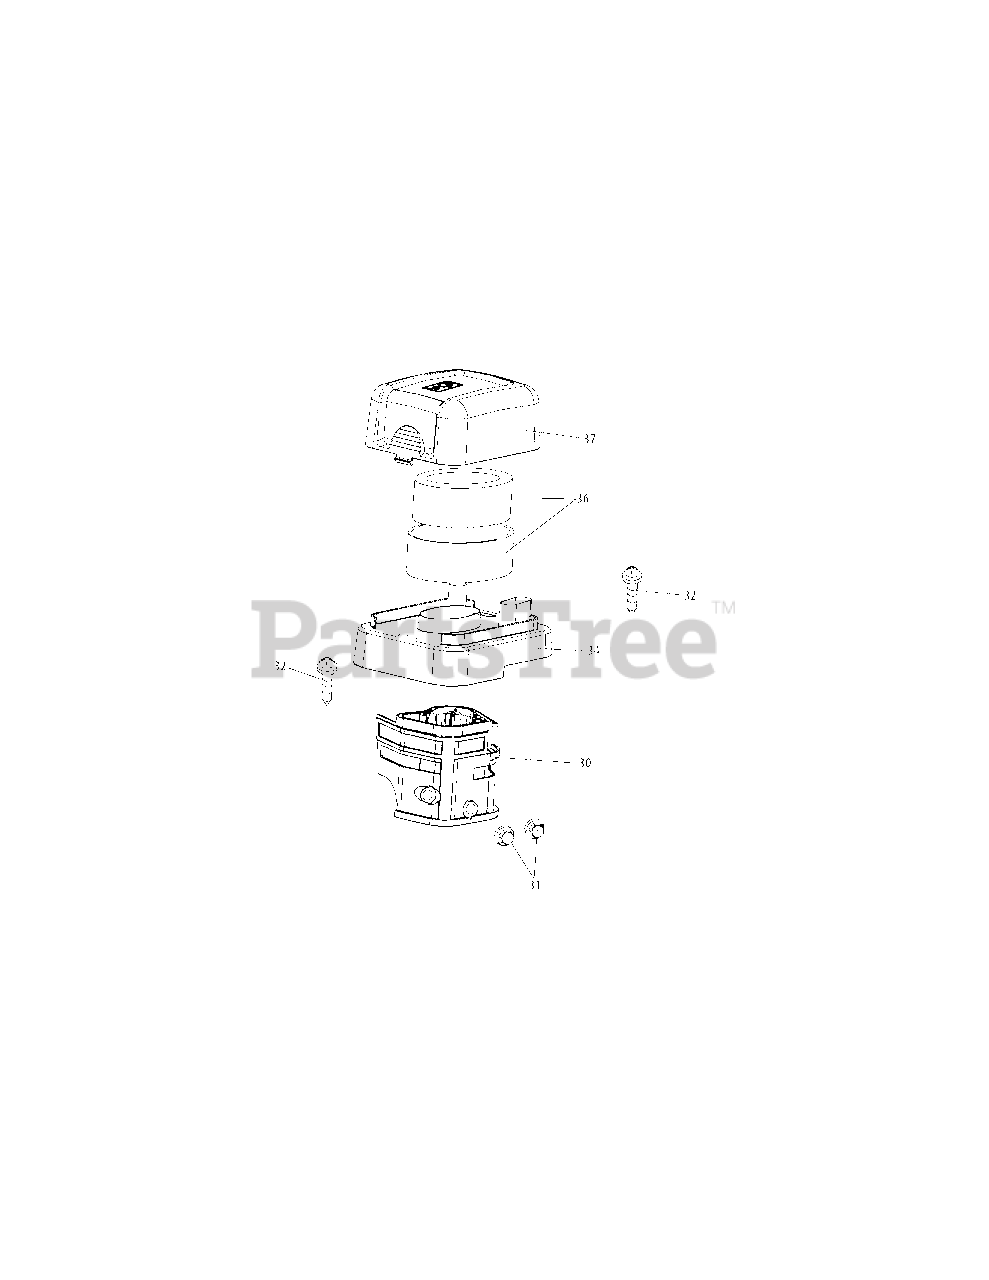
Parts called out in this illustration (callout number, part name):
30	Air Cleaner Housing
32	Self-Tapping Bolt M4.2×16
34	Silencer Plate
36	Air Cleaner Assembly (Filter)
37	Air Cleaner Cover
